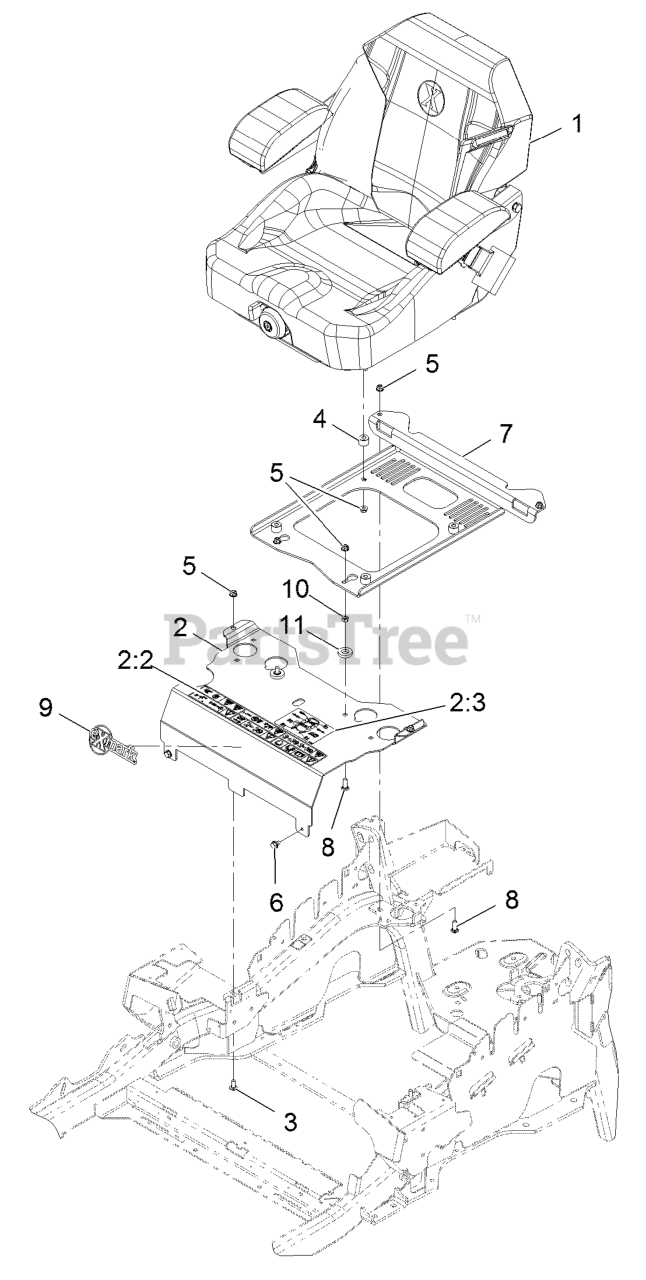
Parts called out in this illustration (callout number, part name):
1	KIT-SUSPENSION SEAT
2	MOUNT-SEAT
2:2	DECAL-CONSOLE
2:3	DECAL-SERVICE AID
3	SCREW-CARR
5	NUT-HF, NI
7	PLATE-SUPPORT, SEAT
8	SCREW-CARR
10	NUT-HEX
